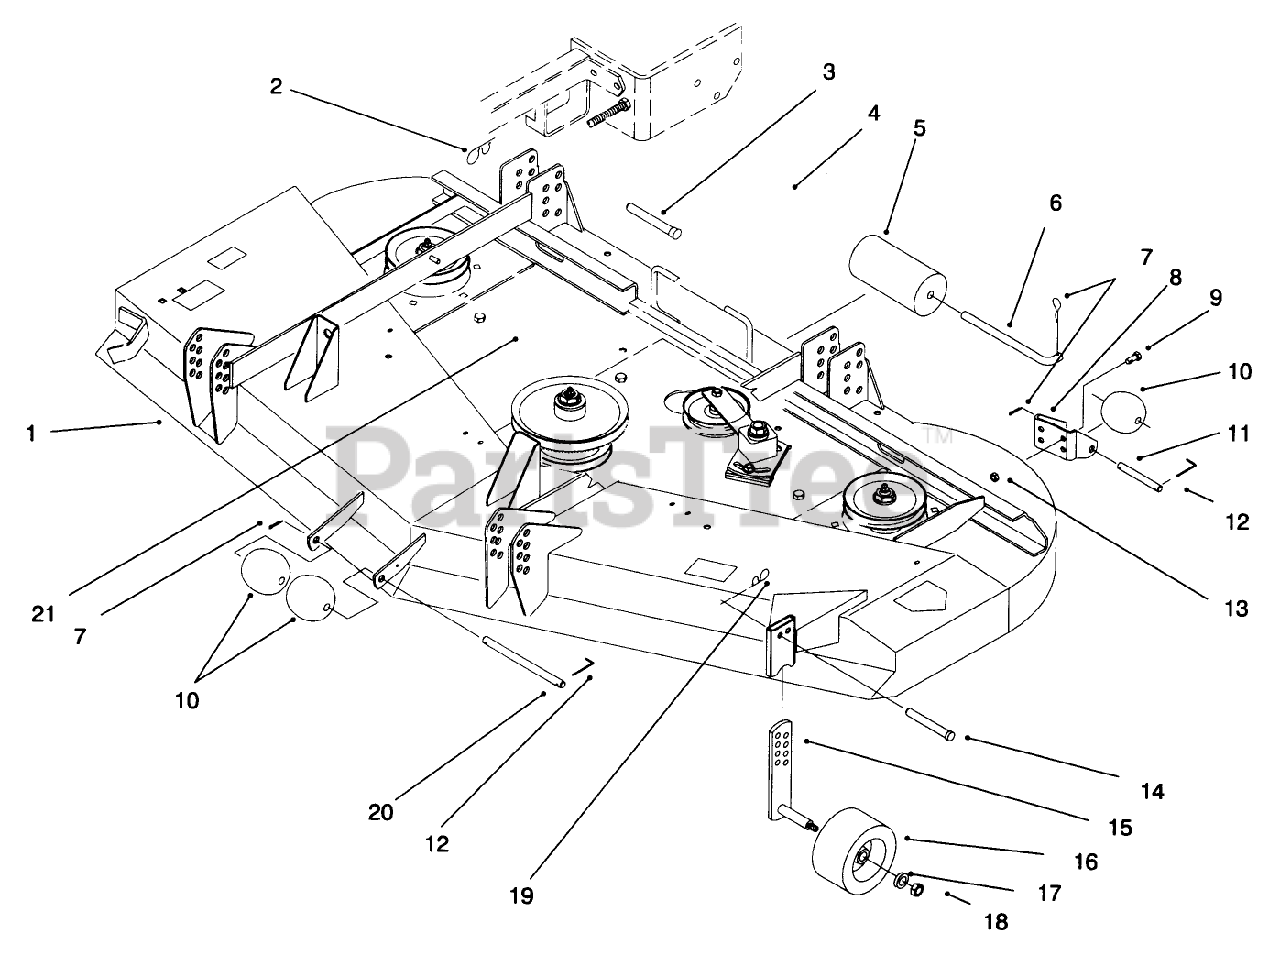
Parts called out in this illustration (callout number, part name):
1	DECK WA W/DECALS
2	PIN-HAIR
3	PIN-CLEVIS
4	V-BELT, DECK DRIVE
5	ROLLER-DECK
6	SHAFT-ROLLER, REAR
7	PIN-COTTER
9	SCREW-HH
10	ROLLER
11	SHAFT-ROLLER
12	PIN-SPECIAL
13	NUT-HHF, WHIZ
14	PIN-CLEVIS
15	GAGE-WHEEL
17	WASHER-FLAT
18	NUT-LOCK, NI
19	PIN-HAIR
20	SHAFT-ROLLER
21	V-BELT
